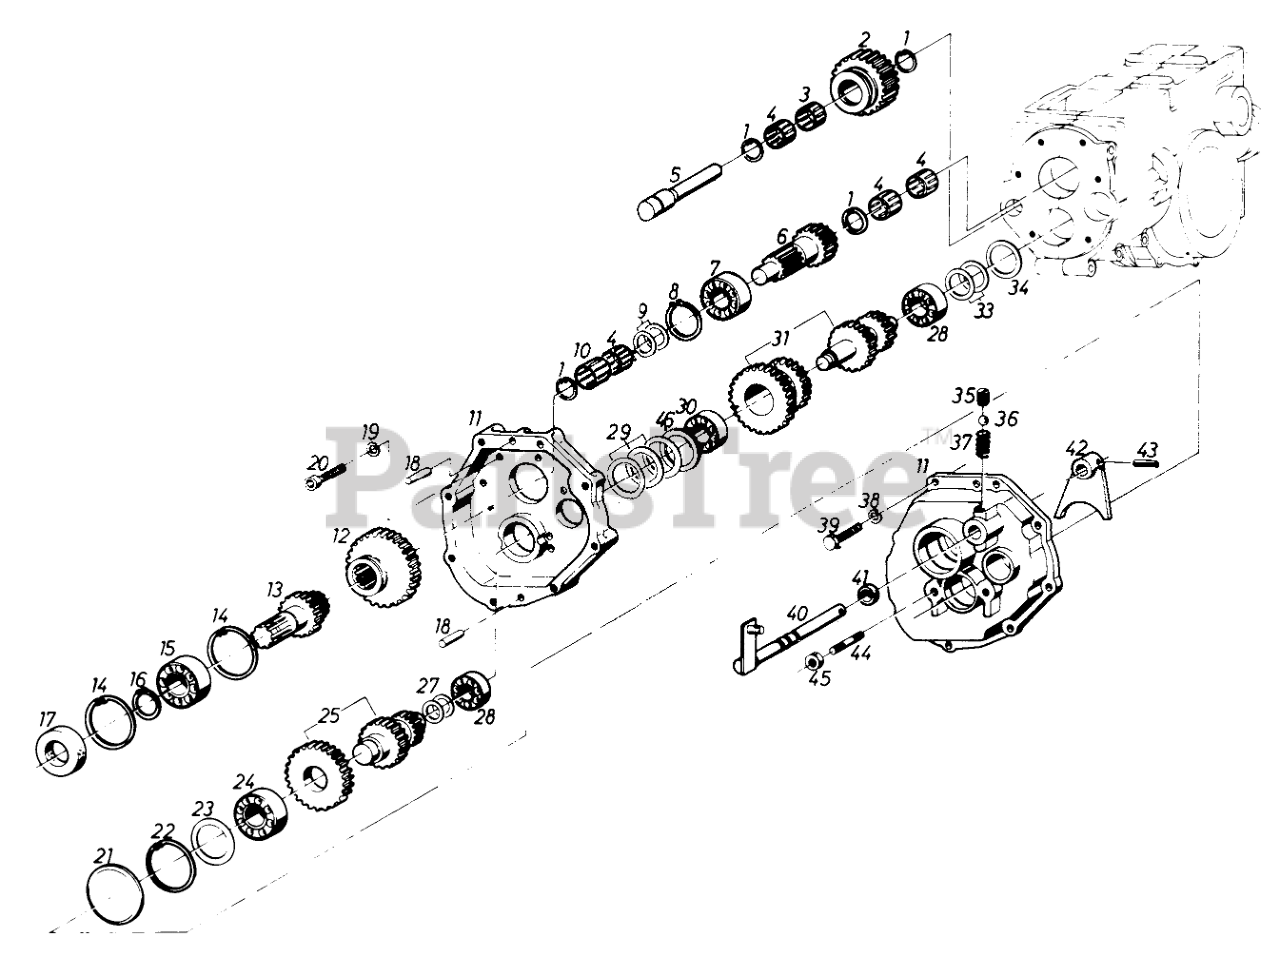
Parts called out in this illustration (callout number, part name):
1	Snap Ring
2	Pinion
3	Needle Cage
4	NEEDLE CAGE
5	Shaft
6	Intermediate Shaft
7	Ball Bearing
8	Retaining Ring
9	Shim (15 X 21 X 0.5 DIN 988)
9	Shim (15 X 21 X 0.2 DIN 988)
10	Needle Cage
11	Multiplier Housing Assy. (Consisting of Parts 11, 18, 38 and 39)
12	Pinion
13	Drive Shaft
14	Retaining Ring
15	Ball Bearing
16	Circlip
17	SEAL RING
18	Roll Pin
19	Schnorr-Lock Washer
20	Screw
21	Cover
22	Circlip
23	Shim
24	Ball Bearing
25	Counter Shaft Multiplier Assy.
27	Shim
28	Bearing
29	Shim
29	Shim (37 X 47 X 0.2 DIN 988)
29	Shim (37 X 47 X 0.5 DIN 988)
30	Ball Bearing
31	Counter Shaft Assy
33	Shim (28 X 40 X 0.1 DIN 988)
33	Shim (28 X 40 X 0.3 DIN 988)
34	Lock Washer
35	Stud
36	Ball
37	Spring
38	Lockwasher
39	Bolt
40	Shift Axle
41	O-Ring
42	Shift Fork
43	Spring Pin
44	Stud
45	Nut
46	Washer
